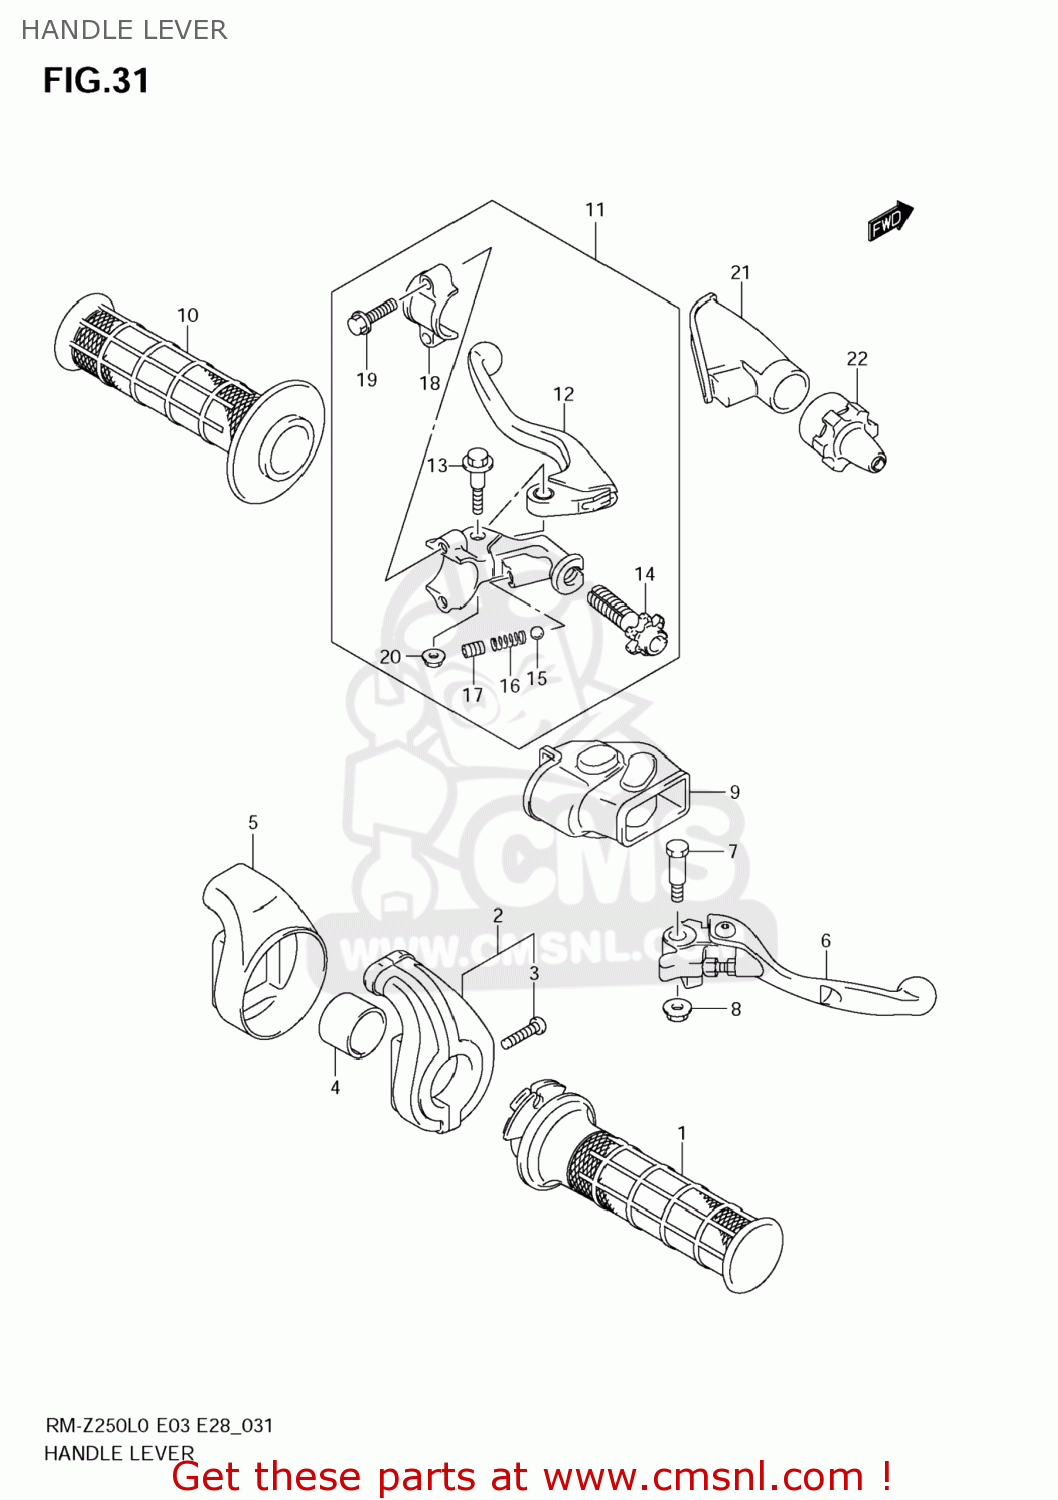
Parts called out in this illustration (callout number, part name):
1	GRIP,THROTTLE
2	CASE ASSY,THROTTLE
3	SCREW,CASE
4	COLLAR,THROTTLE CASE
5	COVER,THROTTLE CASE
6	LEVER ASSY,BRAKE
7	BOLT,BRAKE LEVER
8	NUT
9	COVER,BRAKE LEVER
10	GRIP,L
11	LEVER ASSY,CLUTCH
12	LEVER,CLUTCH
13	BOLT
14	ADJUSTER,CLUTCH CABLE
15	BALL
16	SPRING
17	SCREW(6X8)
18	BRACKET,CLUTCH LEVER HOLDER
19	BOLT,BRACKET
20	NUT
21	COVER,CLUTCH LEVER
22	COVER,CLUTCH ADJUSTER
